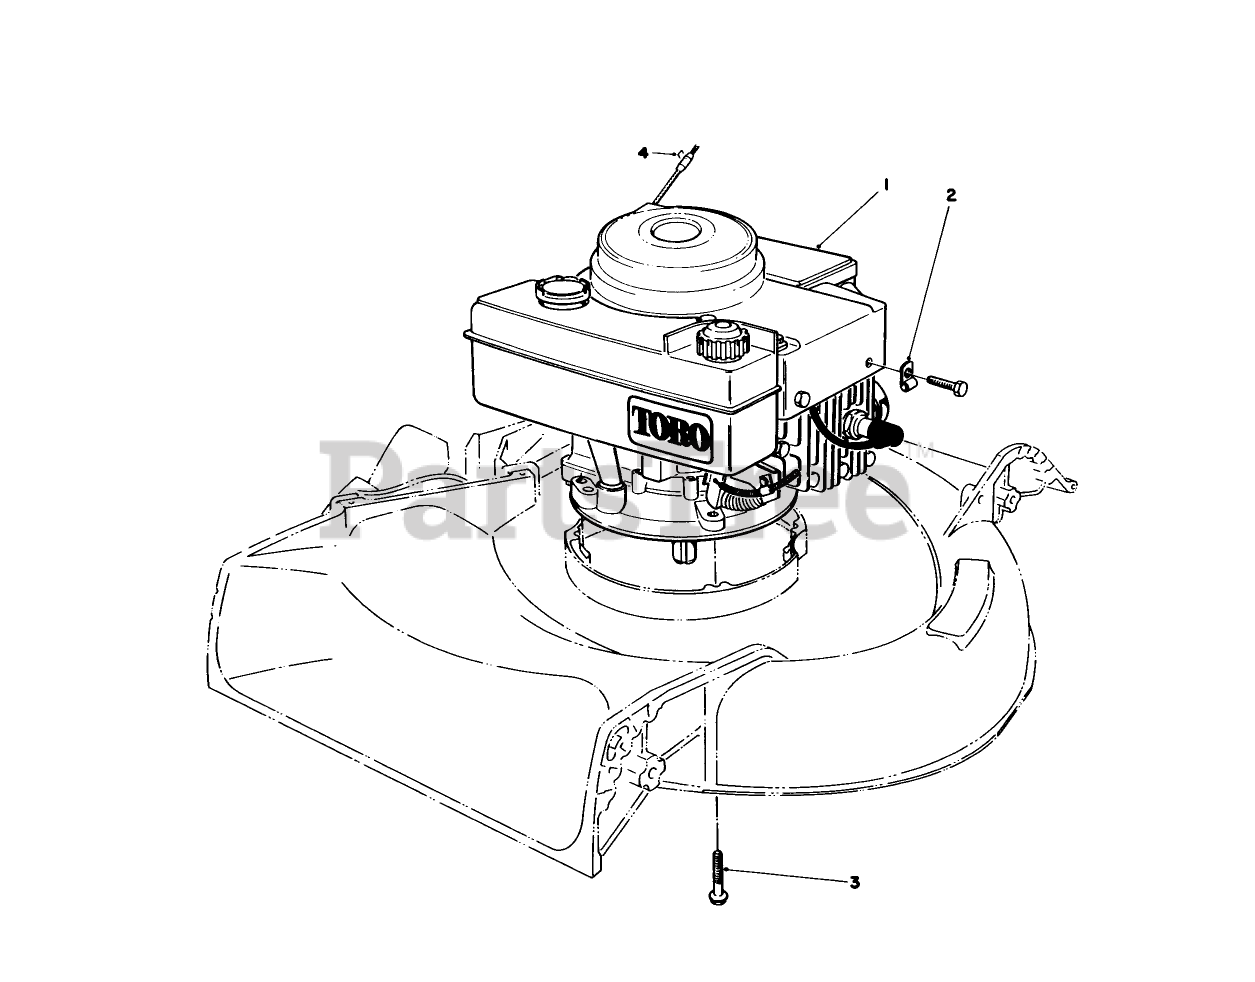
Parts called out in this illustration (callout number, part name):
1	Engine
3	3/8-16 X 2-3/4 CAPSCR
4	Staple
